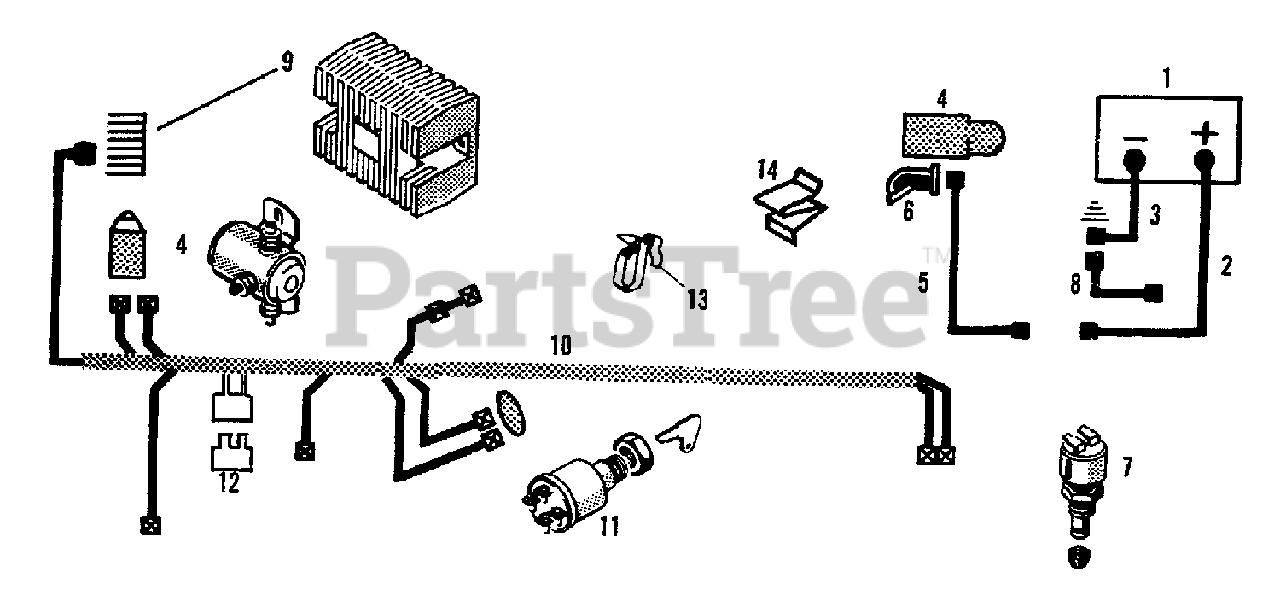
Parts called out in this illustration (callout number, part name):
1	BATTERY, 12 Volt-45 Amp/Hour
2	CABLE, Battery To Solenoid
3	CABLE, Battery To Ground
4	SOLENOID, Starter
4	LOCKWASHER, 5/16
4	NUT, 5/16NC
4	NUT, #10NF
4	LOCKWASHER, #10
5	CABLE, Solenoid To Starter
6	COVER, Terminal
7	SWITCH, Momentary Nuetral
7	NUT, Special
7	BOOT, Rubber
8	CABLE, Solenoid To Engine
9	REGULATOR - RECTIFIER
10	HARNESS, Wiring
11	SWITCH, Ignition
11	KEY, Ignition
11	NUT, Face
11	LOCKWASHER, Internal Tooth
12	BREAKER, Circuit
12	BOLT, 1/4NC x 1, Carriage
13	CLIP, Cable
14	CLIP, Speed
14	SCREW, #10NC x 1-1/4
14	NUT, #10NC
14	LOCKWASHER, #10
